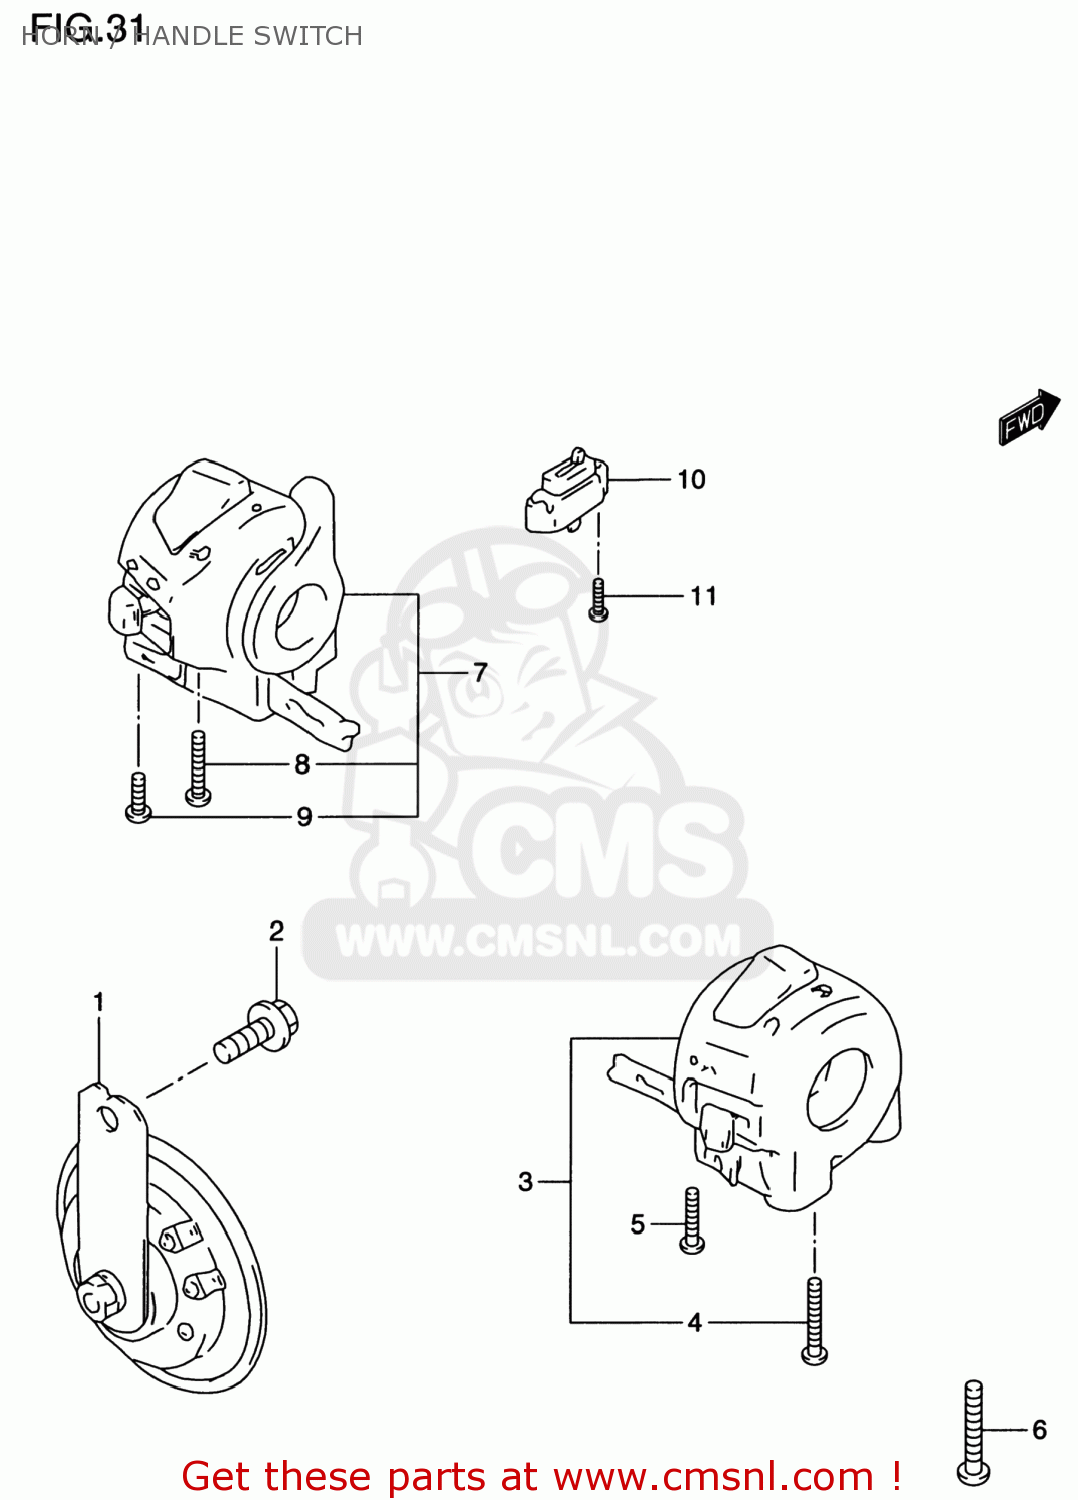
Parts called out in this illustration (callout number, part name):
1	HORN ASSY
2	BOLT
3	SWITCH ASSY,HANDLE,R
4	SCREW
5	SCREW
6	SCREW
7	SWITCH ASSY,HANDLE,L
8	SCREW
9	SCREW
10	SWITCH ASSY,CLUTCH
11	SCREW
